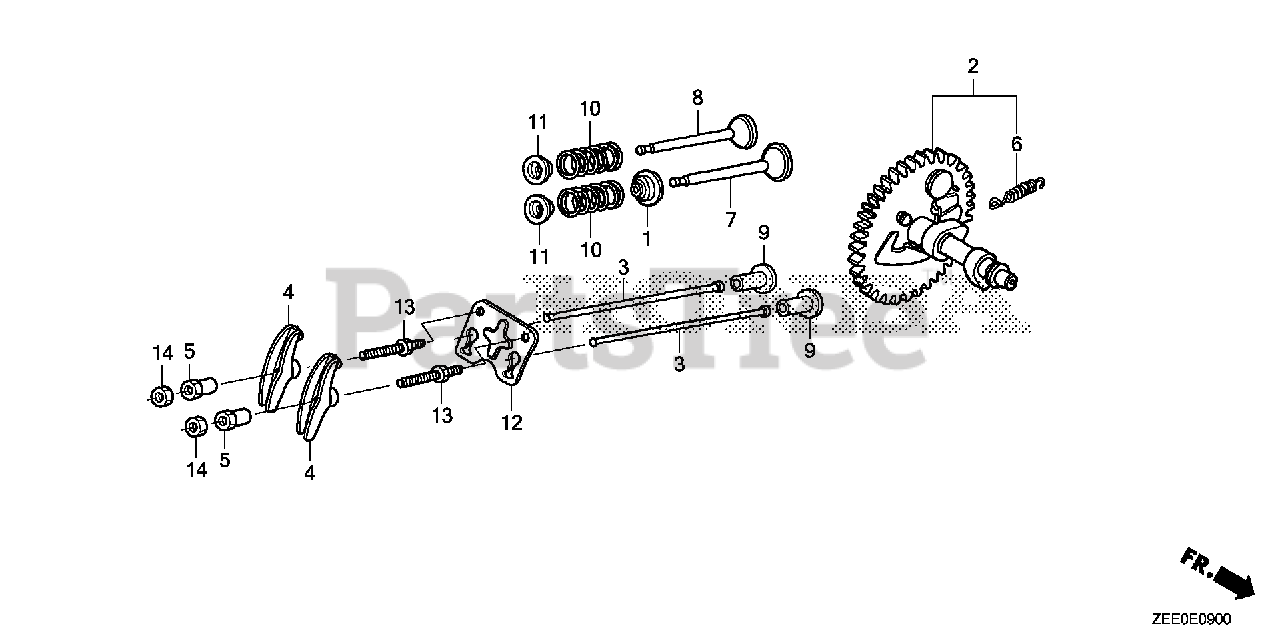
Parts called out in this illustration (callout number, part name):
1	SEAL, VALVE STEM
2	CAMSHAFT ASSY.
3	ROD, PUSH
4	ARM, VALVE ROCKER
5	PIVOT, ROCKER ARM
6	SPRING, WEIGHT RETURN
7	VALVE, IN.
8	VALVE, EX.
9	LIFTER, VALVE
10	SPRING, VALVE
11	RETAINER, VALVE SPRING (EXHAUST SIDE)
11	RETAINER, VALVE SPRING
12	PLATE, PUSH ROD GUIDE
13	BOLT, PIVOT (8MM)
14	NUT, PIVOT ADJ.
